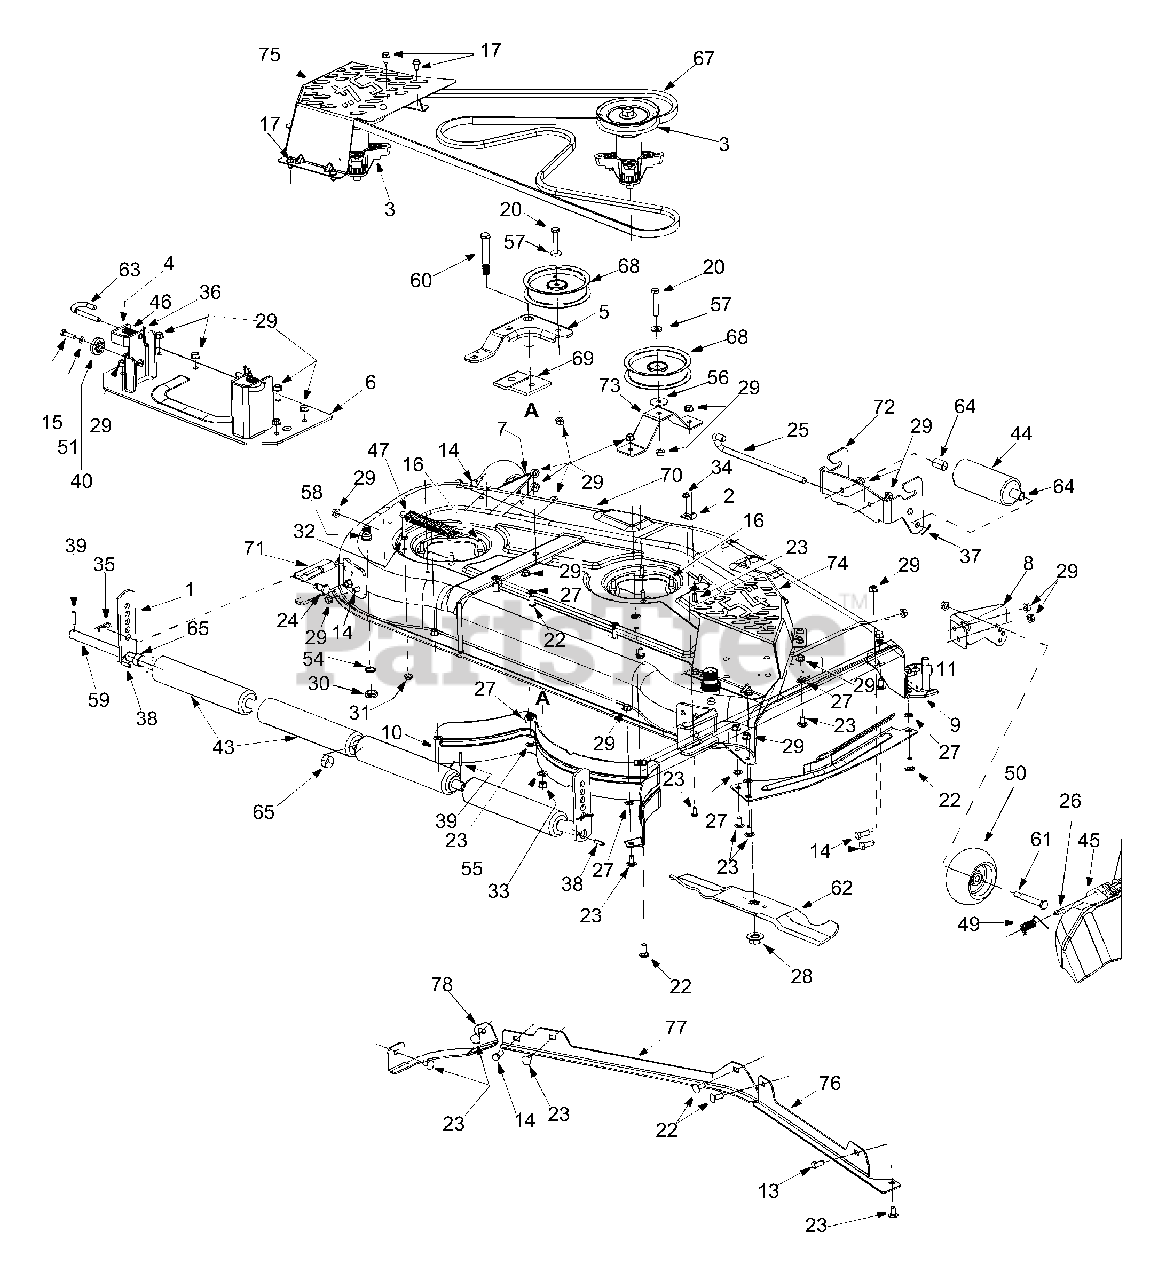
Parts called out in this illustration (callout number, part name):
2	Bracket, Hook, Retainer
3	Spindle Assembly, Pulley, 5.39 Dia x .5625
11	Bracket
12	Guard, Finger
13	Hex Screw 3/8-16 x 0.75
14	Hex Screw 3/8-16 x 1.0
15	Hex Screw, 5/16-18 x 1.25
16	Screw, Self-tapping, 5/16-18 x 1.000
17	Screw, AB, 5/16-12 x 0.75
18	Hex Screw, 1/4-20 x .620
19	Screw, Carriage, 3/8-16 x 5.00
20	Hex Screw, 3/8-16 x 2.25
21	Hex Screw, 5/16-18 x 2.25
22	Bolt, Carriage, 3/8-16 x 1.0
23	Short Neck Carriage Bolt 3/8-16 x .75
24	Pin, Clevis, .50 Dia x .78
25	Pin, Roller, .5" Dia x 10.06
26	Pin, Hinge, Dia .375 x 14.06
27	Push Nut Retainer
28	Nut, Hex Flange, 5/8-18
29	Nut, Flange Lock, 3/8-16
30	Hex Nut M16
31	Nut, Flange Lock, 5/16-18, Gr5
32	Nut, Hex, 5/16-18, Gr5
33	Nut, Hex Lock, 1/2-13
34	Nut, 1/4-20, Hexflg, Lock
35	Pin, Click, .092 x 1.64
36	Pin, Cotter, 1/8 x 1.25
37	Pin, Cotter, 3/32 x 1.25
38	Pin, Sprg, 1/4 Dia x 1.00
39	Pin, Spring, 3/16 x 1.25
40	Adjustment, Deck, Gear
41	Water Nozzle Adaptor
43	Roller, Deck
44	Front Roller
45	Deflector, Chute
46	Spring, Compression, .406 x .531 x 1.75
47	Spring, Extension, .94 Dia x 6.74
48	Spring, Extension, 1.15 Dia x 5.99
49	Torsion Spring .44 I.d. x 2.10
50	Deck Wheel, 5" Dia.
51	Lock Washer
52	Flat Washer, .812 ID x 1.38 OD x .1
53	Flat Washer, .51 ID x 1.5 OD x .07
54	Lock Washer
55	Washer, Lock, 1/2 , Regular Duty
56	Flat Washer .406 ID X 1.5 x 11ga
57	Washer, Flat .38 ID x.93 OD x.110
58	Water Nozzle: Deck Wash-Out System
59	Roller Shaft
60	Shoulder Screw
61	Shoulder Screw, 1/2 Dia x 2.50
62	Blade, 18.50"
63	Deck Release Handle Rod, .375 Dia
64	Spacer .550 ID x .755 OD x 1.1
65	Spacer, .82 ID x 1.00 OD x .53
66	Spacer, .405 x .75 x 3.875
67	Belt, V-Type, B Section
68	Pulley, Idler, 5.0 Dia.
78	LH Extension Skirt
